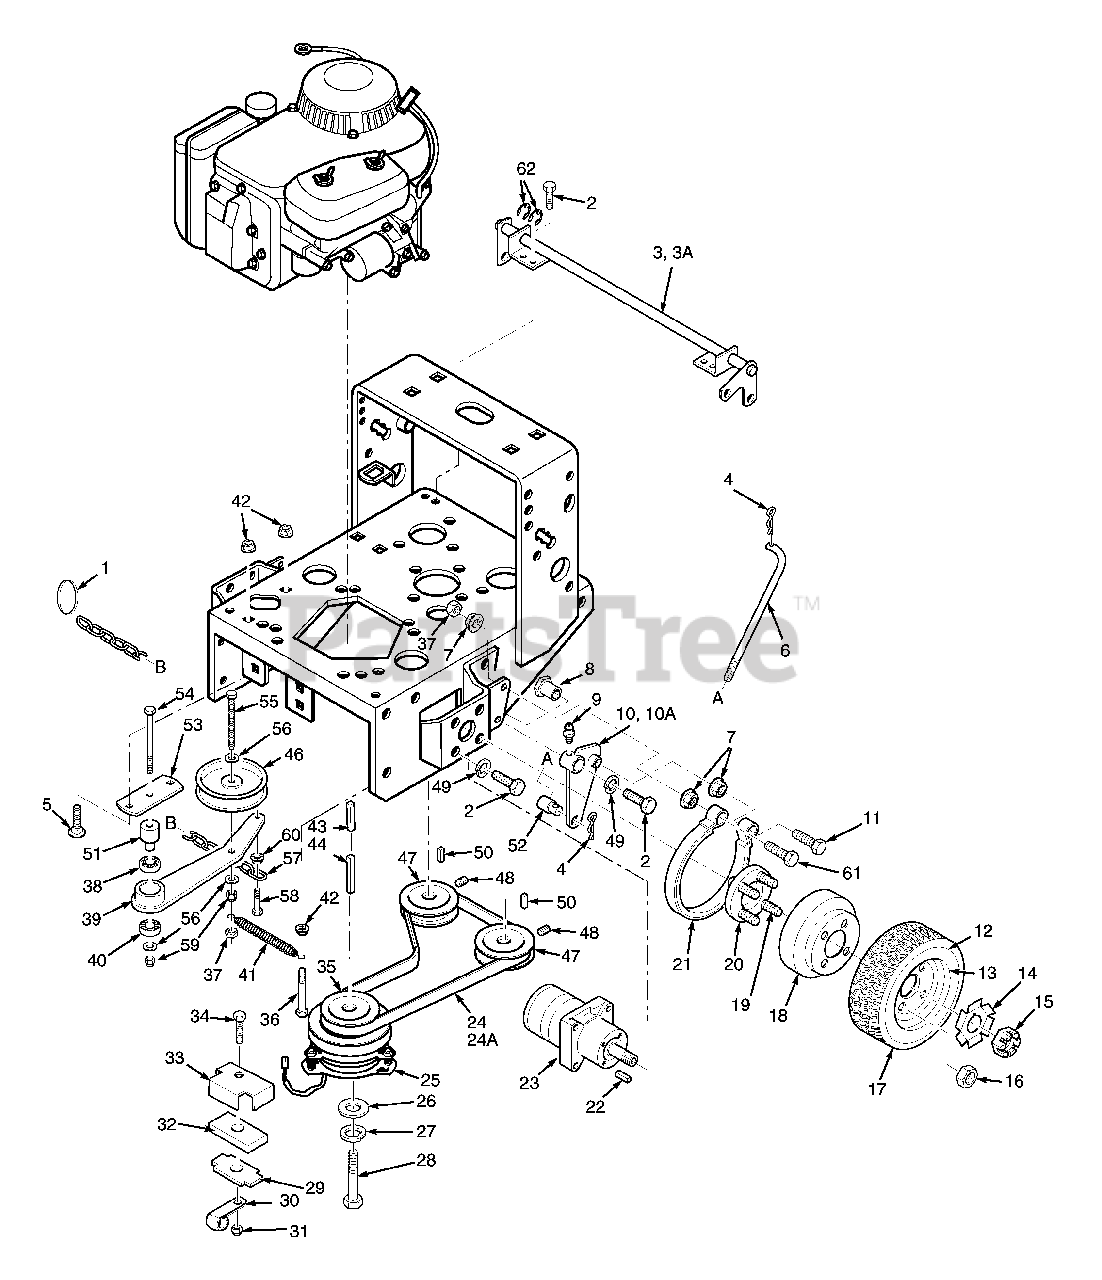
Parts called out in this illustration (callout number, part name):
1	Ring, Split
2	Bolt, 3/8-16 x 1" Hex Head
3	Brake Shaft Assembly Weldment (16" Small Frame)
3A	Brake Shaft Assembly Weldment (20" Large Frame)
4	Hair Pin Cotter, .094 x 1.62
5	Carriage Bolt, 5/16-18 x .75"
6	Rod, Brake Lower
7	Nut, 3/8-16 Serr. Flange
8	Bushing, Brake
9	Grease Fitting
10	Brake Actuator Wlmt., LH
10A	Brake Actuator Wlmt., RH
11	Bolt, 3/8-16 x 2-1/4"
12	Tire, 16 x 6.50, 4 ply
13	Rim Assy
14	Lock Washer, Wheel Motor
15	Hex Castle Nut, 3/4-28 UNEF
16	Nut, Lug
17	Wheel Assy.,
18	Brake Drum
19	1/2-20 Serrated Bolt
20	Hub, Wheel
21	Brake Band, 7.5"
22	Key, 3/16 X .75 Woodruff
23	Wheel Motor
24	Belt, Pump Drive (16" Small Frame)
24A	Belt, Pump Drive (20" Large Frame)
25	Electric Clutch
26	Flat Washer .469 x 1.75 x .25
27	Lock Washer, 7/16
28	Hex Head Bolt, 7/16-20 x 2-3/4"
29	Plate, Backing
31	Nut, 5/16-18 Elastic Stop
32	Rubber Pad, Clutch Stop
33	Retainer, Clutch Stop
34	Hex Head Bolt, 5/16-18 x 1.75"
35	Pulley, Pump Drive Engine
36	Hex Head Bolt, 5/16-18 x 2.75"
37	Nut, 3/8-16 Center Lock
38	Ball Bearings
39	Idler Arm Weldment, Pump
40	Ball Bearings
41	Spring, Pump Belt Idler
42	Nut, 5/16-18 Serr. Flange
43	Key, 1/4x1/4 x 1.00" Clutch Mtg.
44	Key, 1/4x1/4 x 2.75" Pulley Mtg.
45	Flat Washer, 3/8
46	Pulley, Idler 4.5"
47	Pulley, Pump Shaft
48	Setscrew, 5/16-18 x 3/8"
49	Lockwasher, 3/8
50	Key, 5.0 x 5.0 x 25mm
51	Pivot, Idler (Long)
52	Swivel Joint
53	Base, Idler Pivot
54	Bolt, Hex Head 3/8-16 x 3"
55	Bolt, Hex Head 3/8-16 x 2.75"
56	Flatwasher 3/8"
57	Chain
58	Bolt, Hex Head 1/4-20 x 1.25"
59	Nut, Hex Elastic Stop 3/8-16
60	Nut, Serrated Flange 1/4-20
61	Bolt, Hex Head 3/8-16 x 2.63"
62	Retaining Ring, 3/4" Ext. "E"
